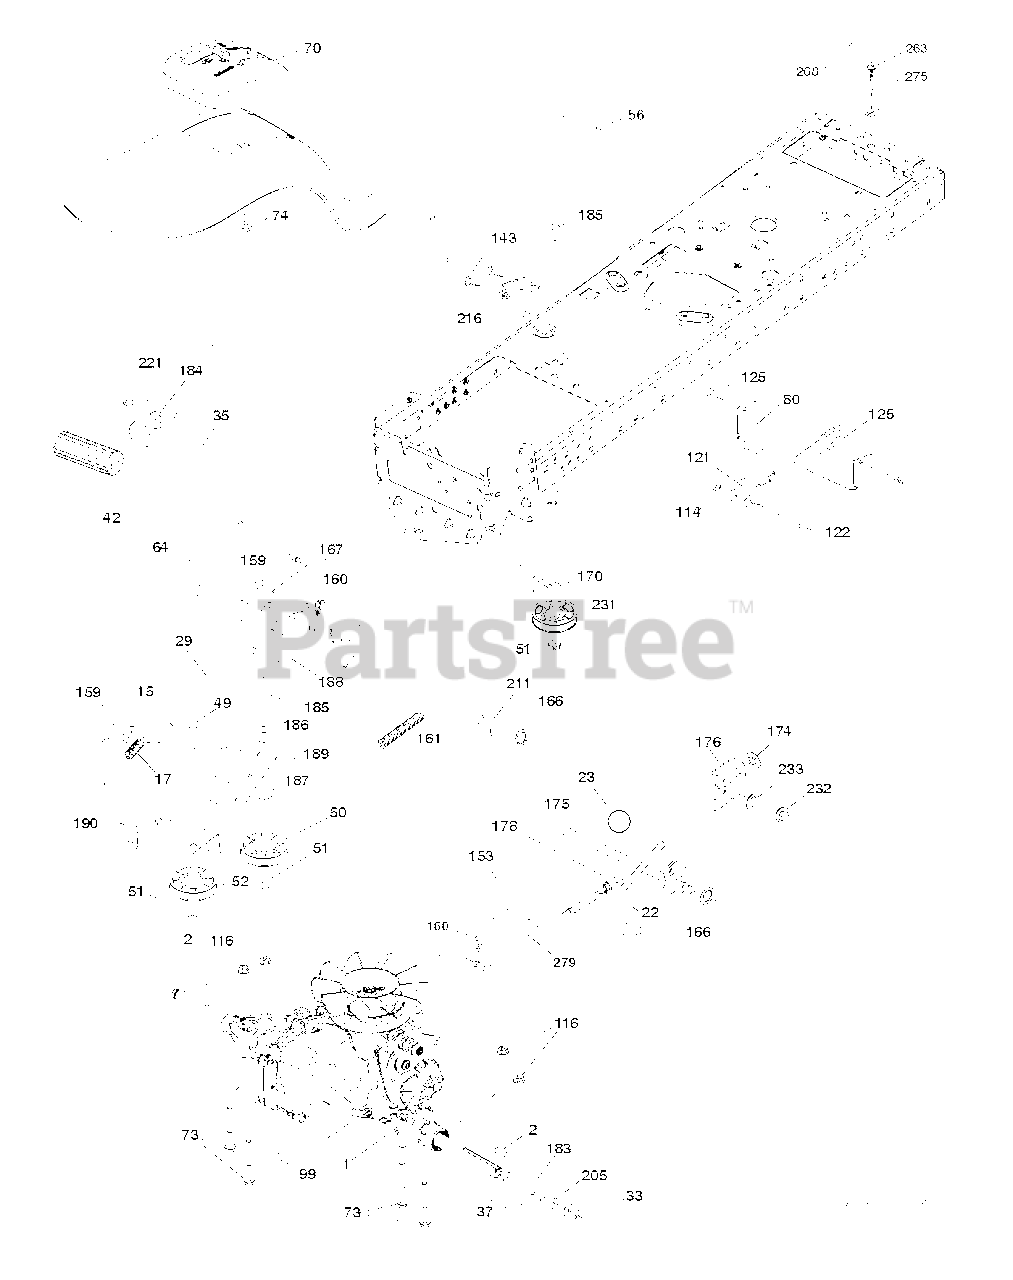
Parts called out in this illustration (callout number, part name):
2	SQUARE KEY
17	SPRING.BRAKE.HG3000/3500
22	ROD.SHIFT.FENDER.TLT.2006
23	KNOB.DUCKHEAD.1/2
29	ROD.BRAKE.T2.TEX
33	E-RING LT
35	ROD, BRAKE, PARK
42	PEDAL COVER T
49	BOLT
50	IDLER.FLAT.910.OFFSET
51	NUT LOCK FLG 3/8-16 UNC
52	IDLER.V-GROOVE.910.OFFSET
56	Ground Drive Belt, T2 HP CE
64	SHAFT.ASM.PEDAL.BRAKE.
70	CONSOLE.SHIFT.STL.HYD.BLACK
73	BOLT HEX 5/16-18 GR 5
74	SCREW.HI-LO.CONSOLE
80	Strap.Torque.T2
99	ROD.SPRING.BYPASS.K46.LT.Z
114	NUT.71038.31-18.HEX.NYLOCK
116	NUT LOCK HEX FLANGE 5/16-18
121	BRACKET STRAP TORQUE
122	BOLT.5/16-18X2.5
125	SCREW
153	RETAINER M
159	COTTER PIN
160	RETAINER CLIP
161	SPRING, RETURN LT
166	NUT.PUSH.625
167	LATCH.BRAKE.SPRING
170	KEEPER.CENTER SPAN.1.688
174	NUT.PUSH.500.2006
175	SHAFT.ASM.SHFT.T2.TLT
176	ARM.CLEVIS.ROD.SHIFT
178	SPRING.SHIFT.GT2006
183	SPACER, AXLE PVST
184	HANDLE.PARKING.BRK.PRED.LT.RED
186	SPACER.RETAINER
187	WASHER 12/32X2X10GA
188	LINK.CLUTCH.GROUND.DRIVE
189	BELLCRANK.GROUND.DRIVE.TEX.
190	KEEPER.BELLCRANK.DRIVE
211	BUSHING.SHAFT.BRAKE.HAND
216	BRACKET.PULLEY.IDLER.W/TEX
221	RETAINER.SPRING.CLIP.H
231	IDLER.V-GROOVE.1.688.OFFSET
232	BOLT FIN HEX 7/16-14 X 1
233	WASHER SERRATED
263	SCREW, 3/8-16X3/4
275	WASHER
279	LINK.SHIFT.T2
